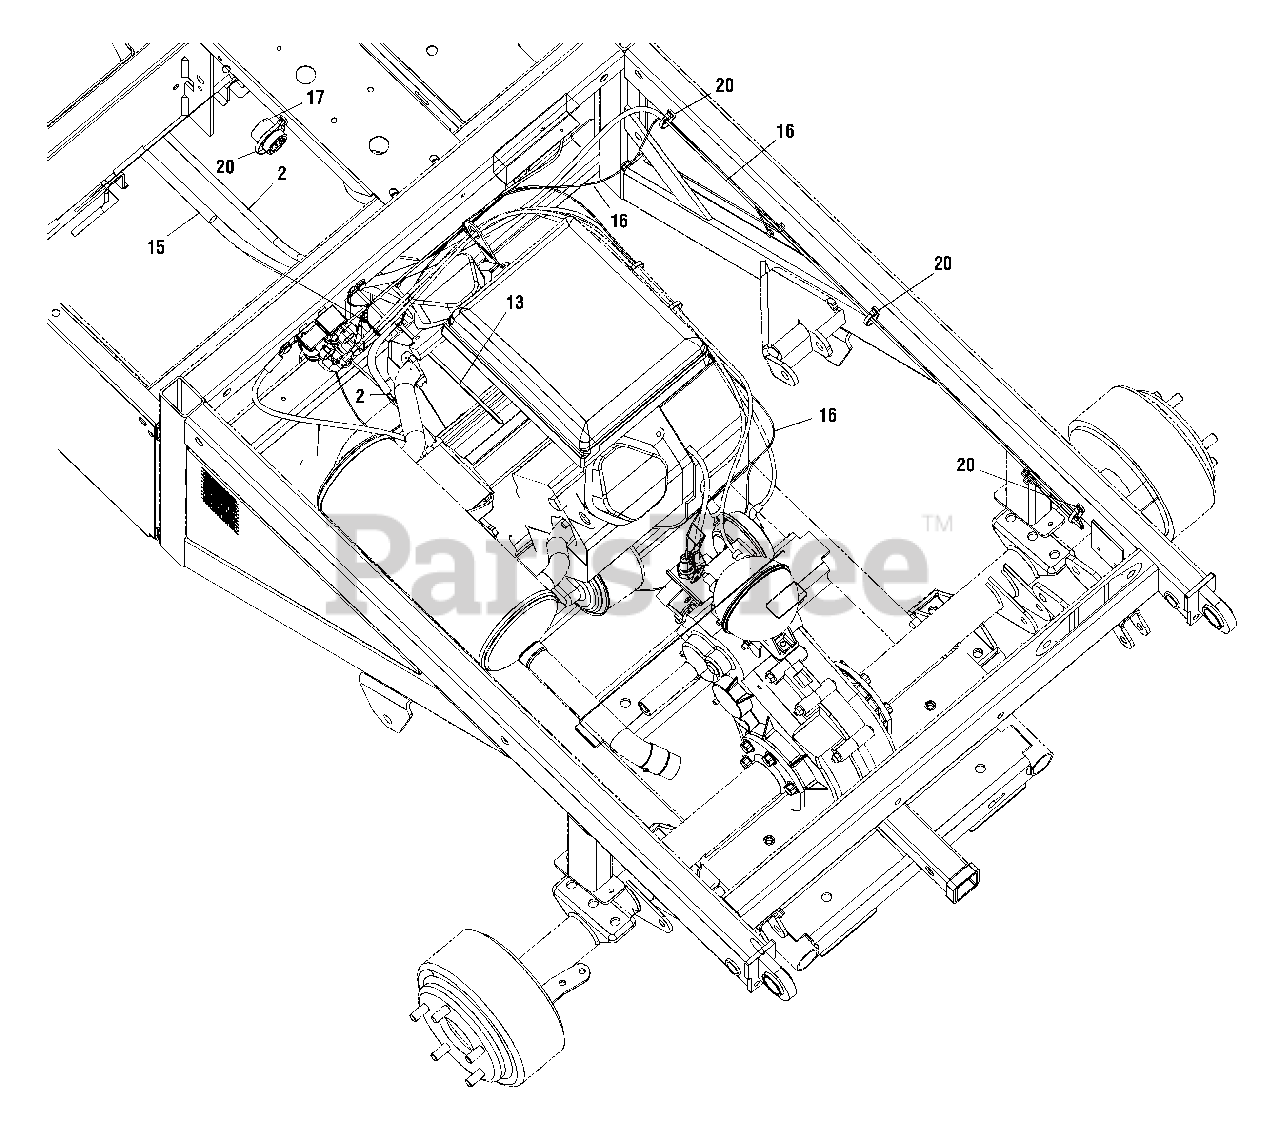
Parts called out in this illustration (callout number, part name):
1	Bracket, Retainer Hook
2	Harness Assembly, Starter
3	Harness Assembly, Motor Ground
4	Screw, 1/4-20 x .50
5	Screw, Self-tapping, 1/4-20 x 0.500
6	Screw, Self-tapping, 5/16-18 x .50
7	Screw, Hex Carriage, 1/4-20 x .75
8	Screw, Self-tapping, 1/4-20 x 1.000
9	Screw, #10-24 x 0.75
10	Nut, Hex Sems, 1/4-20
11	Cover, Protective
12	Strap, Battery
13	Cable Tie, 3/16 x .05 x 7.4
14	Control, Shaft
15	Harness, Utility Main
16	Harness, Motor
17	Control, Reverse
18	Switch
19	Battery
20	Cable Tie, .19 x 8.39 Tree Mount
21	Clip .250 Dia.
23	Rectifier Assembly, Regulator (20A)
24	Retainer Clip, .250 x .267
